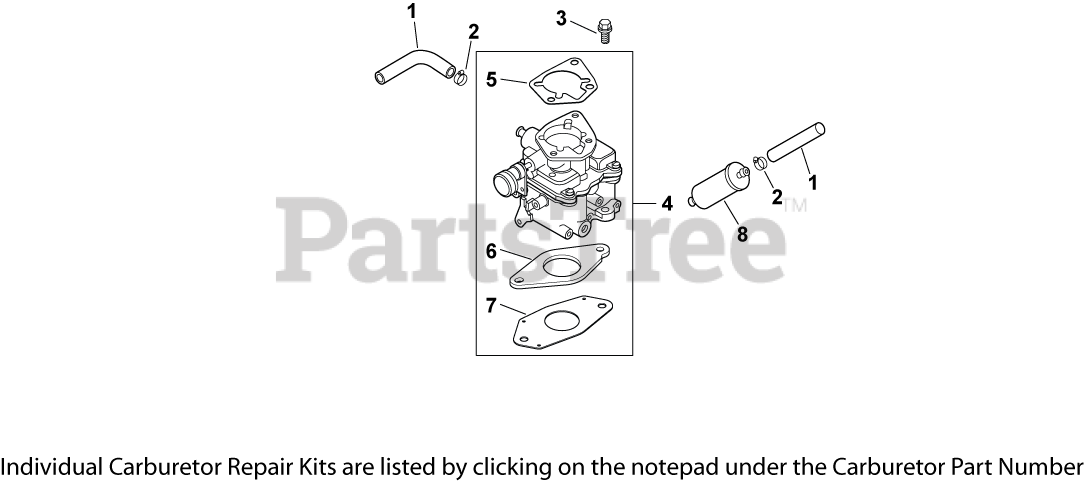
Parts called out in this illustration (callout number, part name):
1	HOSE,LW PERM.FUEL 24.00"-USE 25 111 81-S
2	CLAMP, HOSE (KM)-USE 25 237 31-S
3	SCREW, FLG M6X1.0X25
4	KIT, CARBURETOR W/GASKETS KSF
5	GASKET, AIR CLEANER BASE
6	GASKET, CARBURETOR
7	GASKET, CARBURETOR
8	FILTER, FUEL
